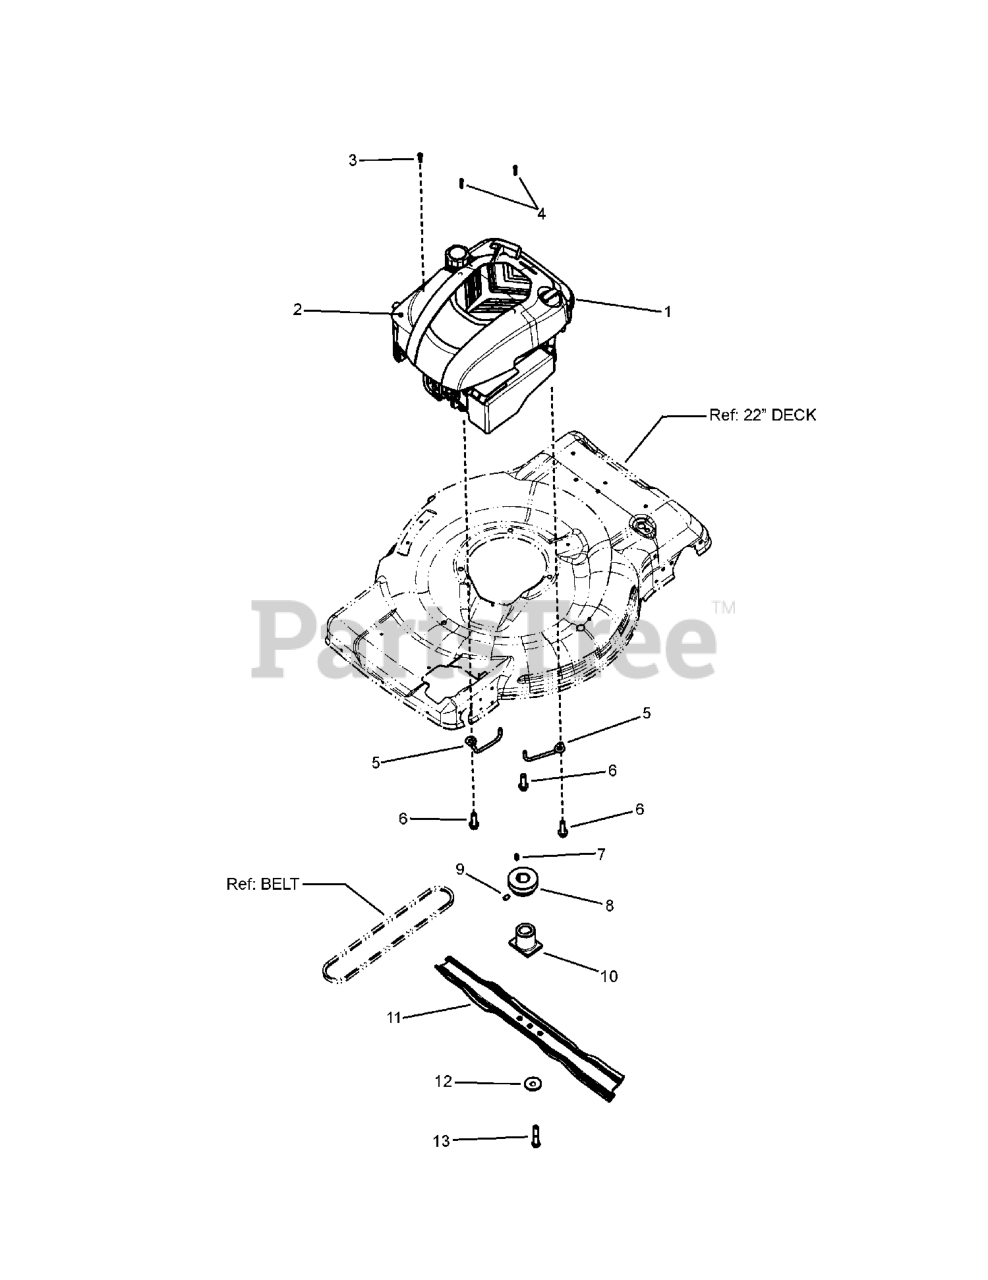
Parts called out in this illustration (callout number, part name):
1	ENGINE, 700 SERIES QUANTUM, DEERE
2	COVER, CONTROL (P-290 BLACK)
3	SCREW, PAN HEAD THREAD ROLLING
4	SCREW, PAN HD CROSS RECESS, TAPPING
5	BELT GUIDE, ENGINE, FWD
6	HWST, 3/8-16 X 1.25
7	KEY, #HP-506 HI-PRO
8	PULLEY, ENGINE
9	HRSS 5/16-18X1/2
10	HUB, BLADE, 21" WBM, RD, 2 POSITION
11	BLADE, WAVE, STEEL DECK
12	WASHER, CONE
13	HHCS, 3/8-24X2 GR5
